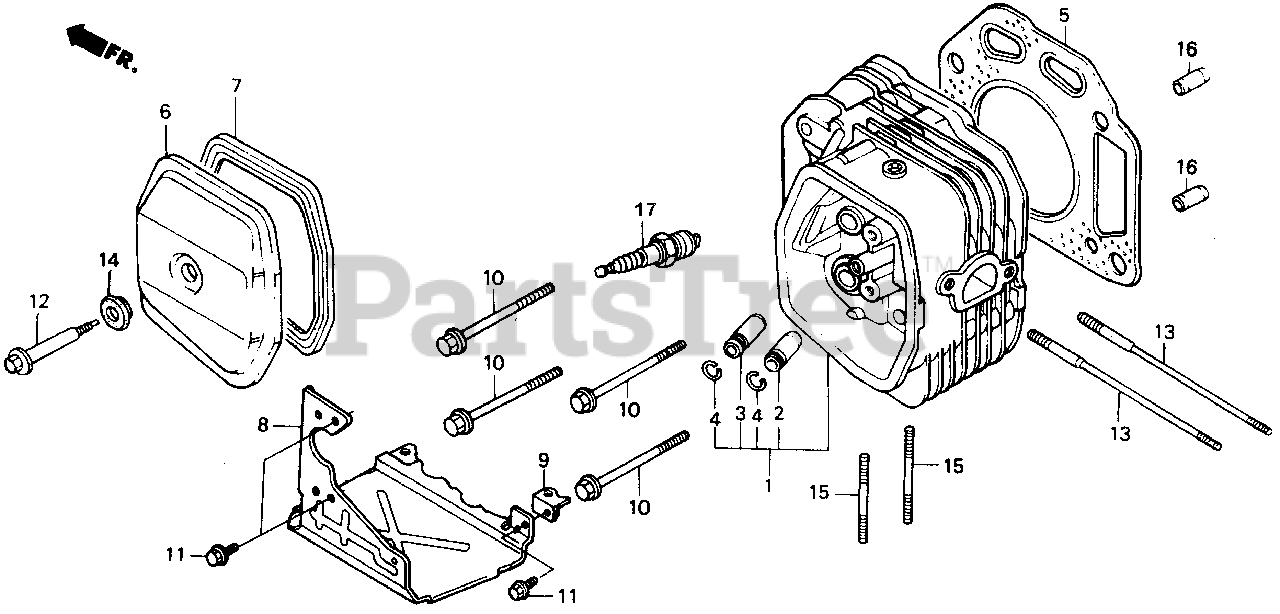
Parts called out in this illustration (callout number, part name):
1	CYLINDER HEAD
2	GUIDE, VALVE (OVER SIZE)
3	GUIDE, EX. VALVE (OVER SIZE)
4	CLIP, VALVE GUIDE
5	GASKET, CYLINDER HEAD
6	COVER, HEAD
7	GASKET, HEAD COVER
8	COVER (LOWER)
9	STAY, COVER (LOWER)
10	BOLT, FLANGE (10X85)
11	BOLT, FLANGE (6X12) (CT200)
12	BOLT, HEAD COVER
13	BOLT, STUD (8X131.5)
14	WASHER, HEAD COVER
15	BOLT, STUD (8X32)
16	PIN, DOWEL (12X20)
17	SPARK PLUG (BPR5ES) (NGK)
17	SPARK PLUG (W16EPR-U) (DENSO)
